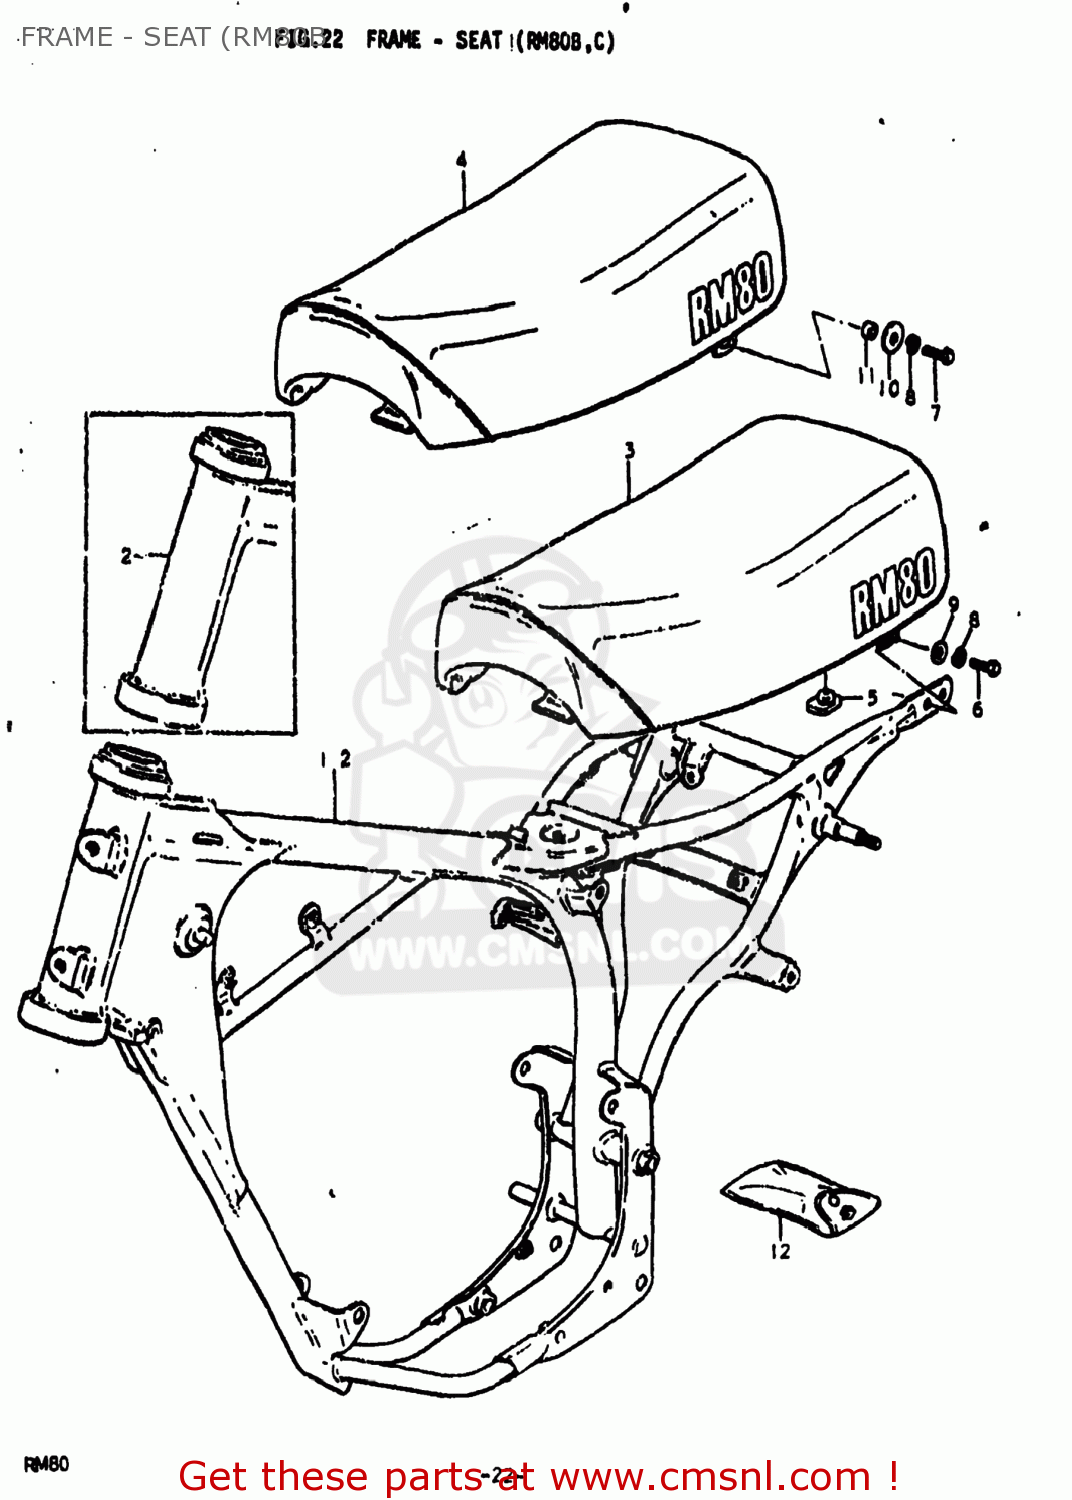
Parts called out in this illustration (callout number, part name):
1	FRAME
2	FRAME
3	SEAT ASSEMBLY
4	SEAT ASSEMBLY
5	CUSHION
6	BOLT, UPPER
7	BOLT
8	LOCK WASHER
9	WASHER
10	WASHER
11	SPACER
12	TOOL SET
